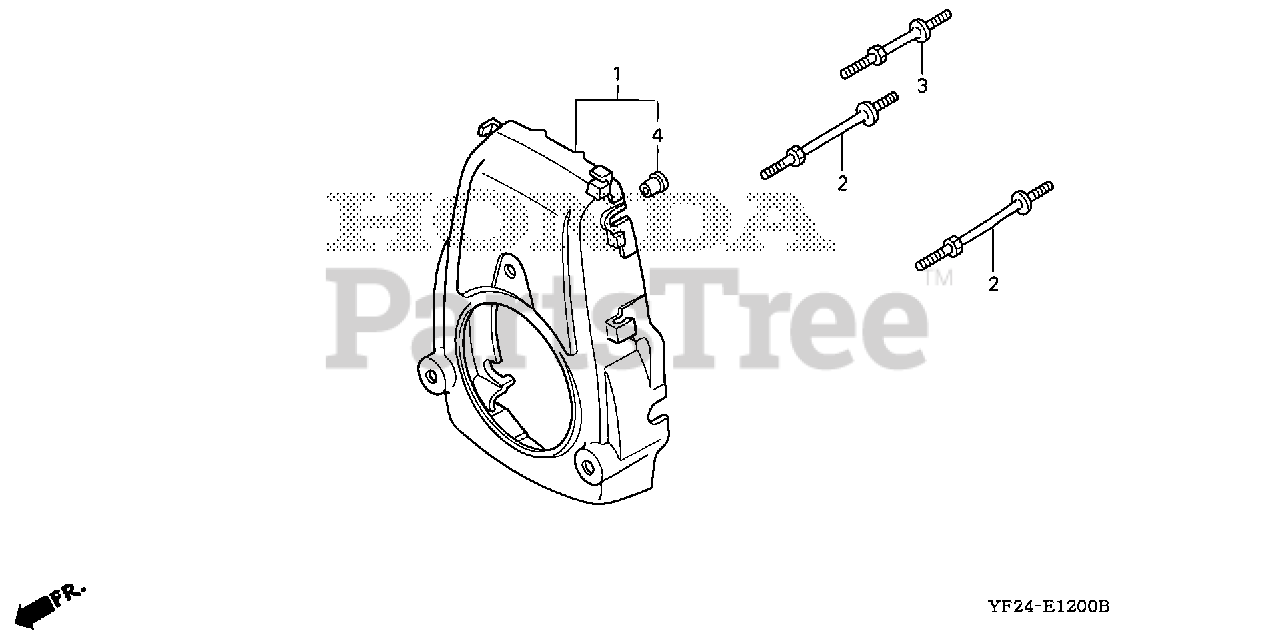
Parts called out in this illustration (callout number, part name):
1	COVER, FAN *R280* (POWER RED)
2	BOLT A, STUD
3	BOLT B, STUD
4	COLLAR, FAN COVER
